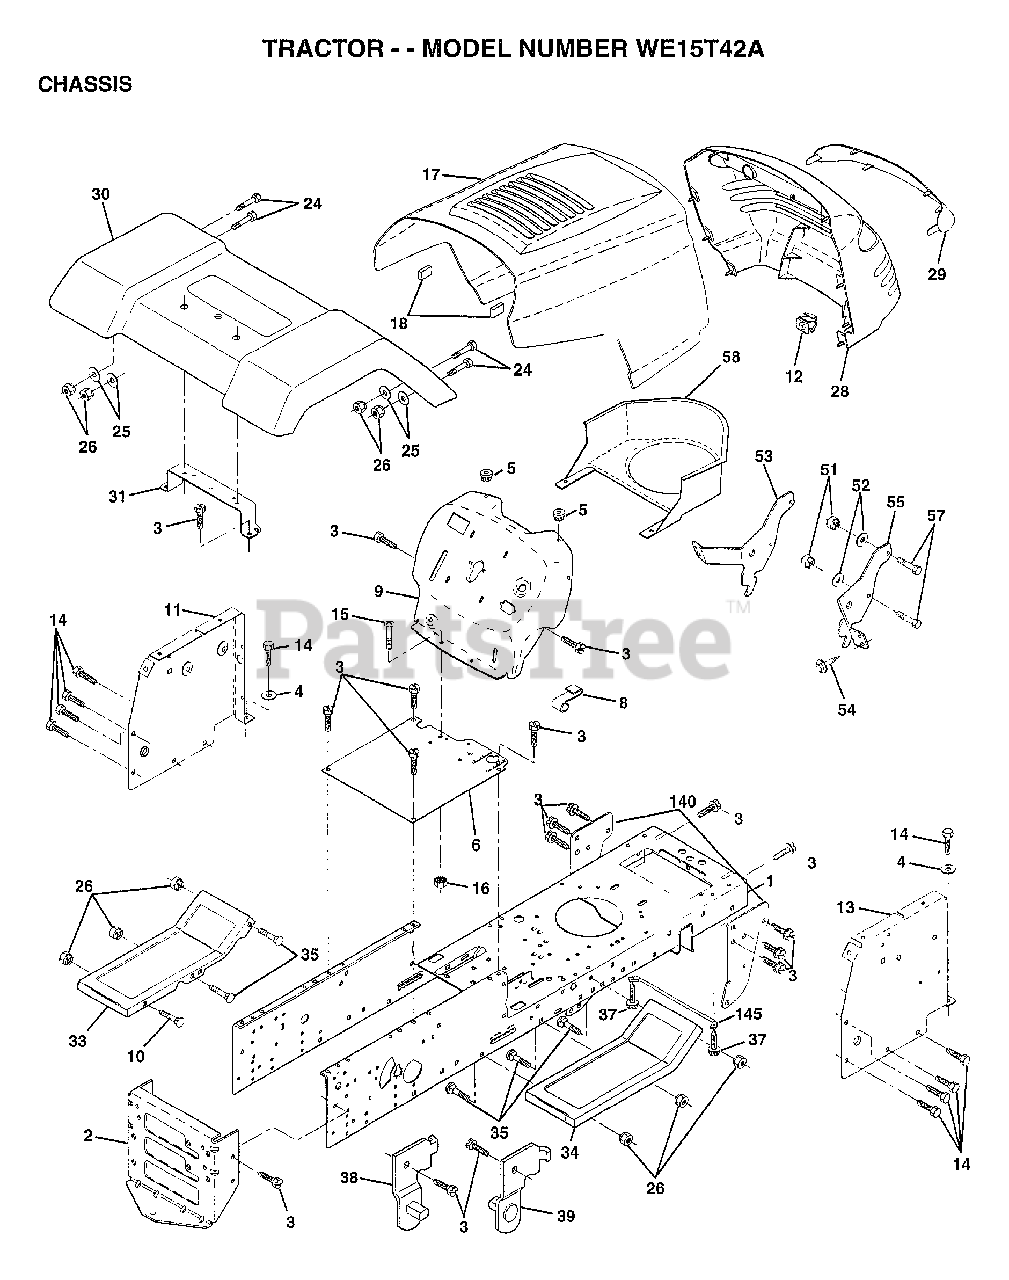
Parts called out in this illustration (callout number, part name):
1	CHASSIS.STAMPING
3	SCREW
4	WASHER
5	BUMPER-HOOD/DASH
6	SADDLE
8	CLIP.RETAINER
9	DASH SILKSCREEN
11	"PANEL-DASH,LH"
12	CLIP.TINNERMAN
13	PANEL.ASM.SLKSCR.DASH.RH
14	SCREW LT
15	SCREW
17	HOOD.STEEL.ASSY
24	BOLT
25	WASHER
26	NUT
28	GRILLE-MS428
29	LENS.GRILLE.PRIVATE LABEL
30	FENDER.PNTL.LT.W/O.SHIFT
31	BRKT FENDER
33	FOOTREST.LH.PERF.
34	FOOTREST.RH.PERF.
35	BOLT
37	SCREW LT
38	BRACKET ASM LH
39	BRACKET ASM RH
51	NUT
52	WASHER
53	BRACKET.GRILLE.LH
54	SCREW.HEX.WS.HD
55	BRACKET.GRILLE.RH
58	AIR DUCT
140	BRKT SUSPENSION
145	"ROD POVOT,CHASSIS"
